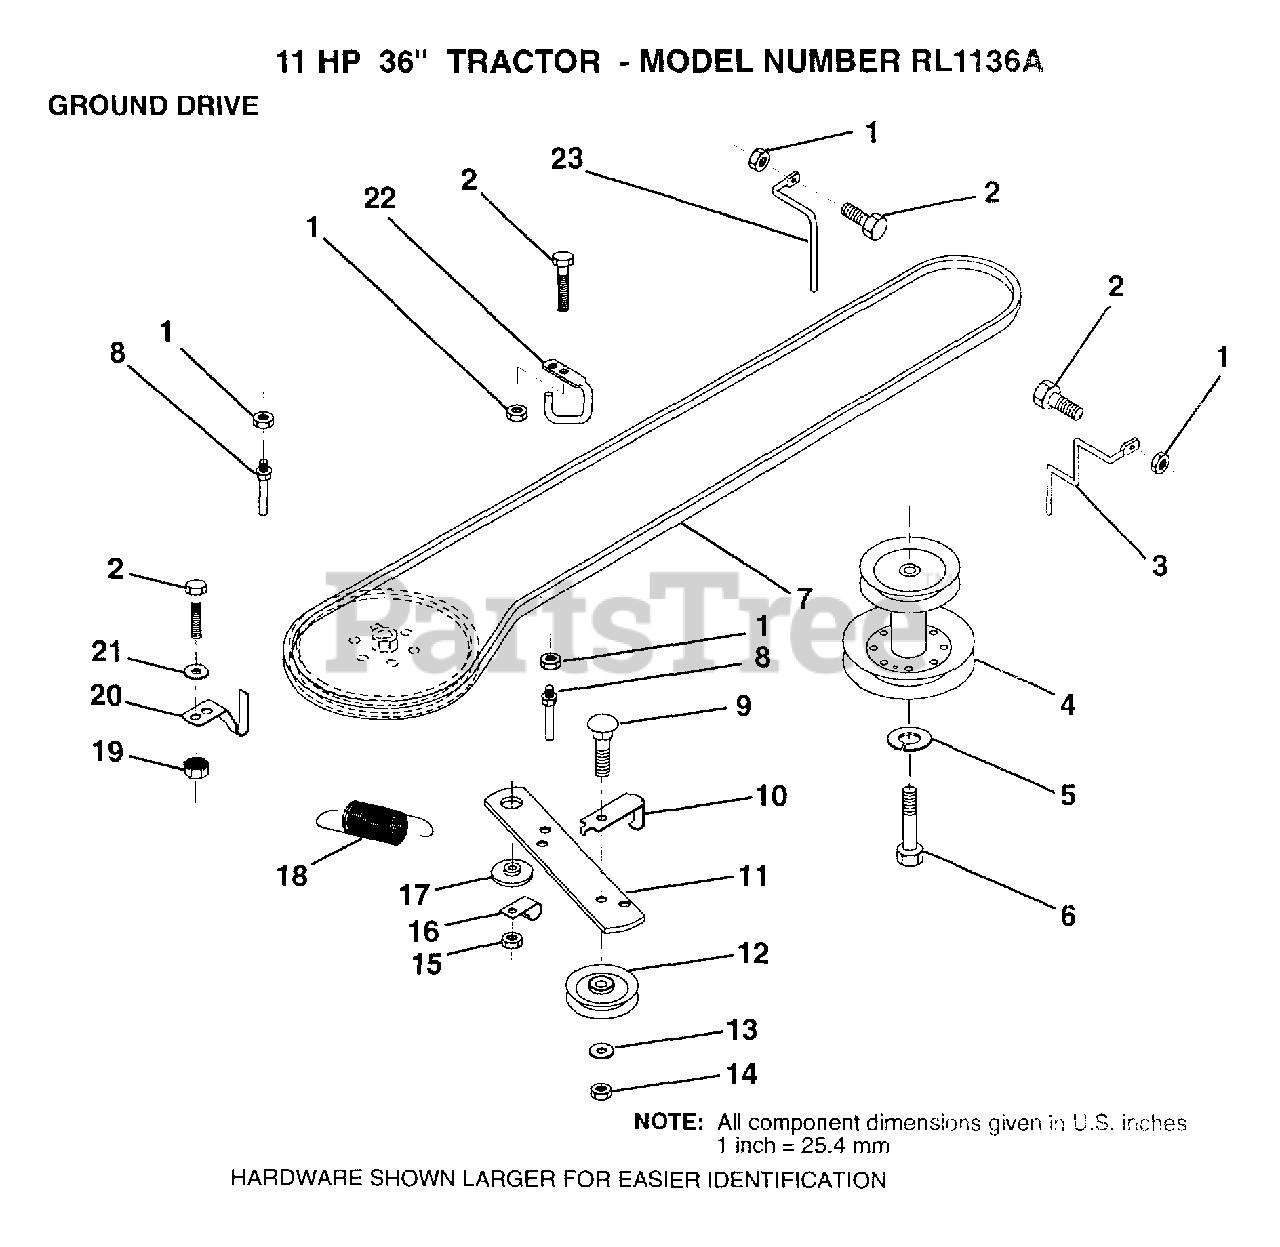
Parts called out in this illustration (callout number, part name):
2	BOLT
4	PULLEY.ENGINE.LR
5	LOCKWASHER
6	HEX BOLT
7	BELT
8	"KEEPER,DRIVE BELT"
9	BOLT
10	"KEEP,IDLER DR BEL"
12	PULLEY.IDLER.FLAT
13	WASHER
14	LOCKNUT
16	"CLIP,INSULATOR"
17	SPACER RETAINER
20	"KEEPER,DR BELT "
21	WASHER
22	"KEEPER,FRA DR BEL"
